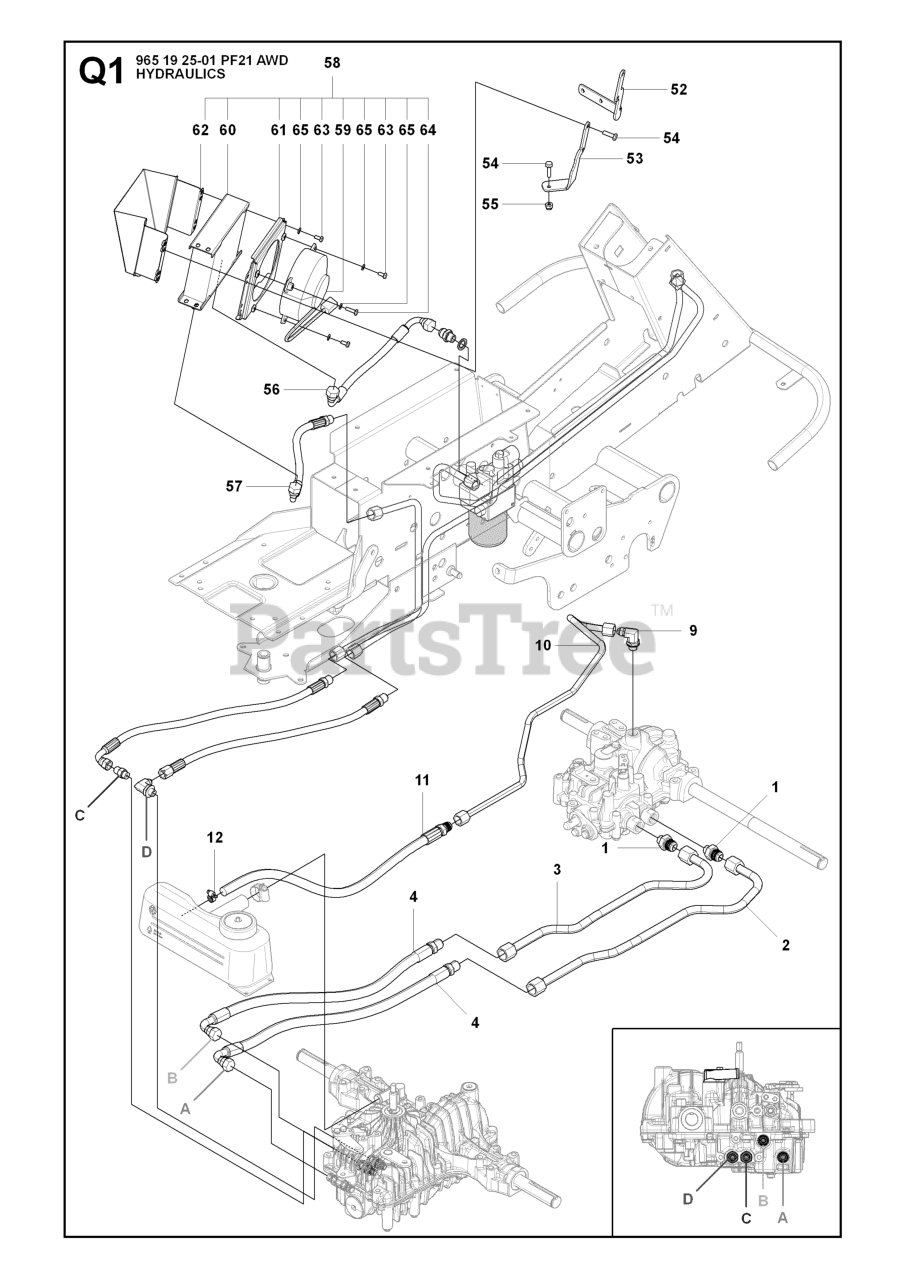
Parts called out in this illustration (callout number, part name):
1	PIPE FITTING
12	CLAMP
51	HOSE GUARD D=43 L=400
54	SCREW EHHFM
55	LOCKNUT M6
65	WASHER - M6
